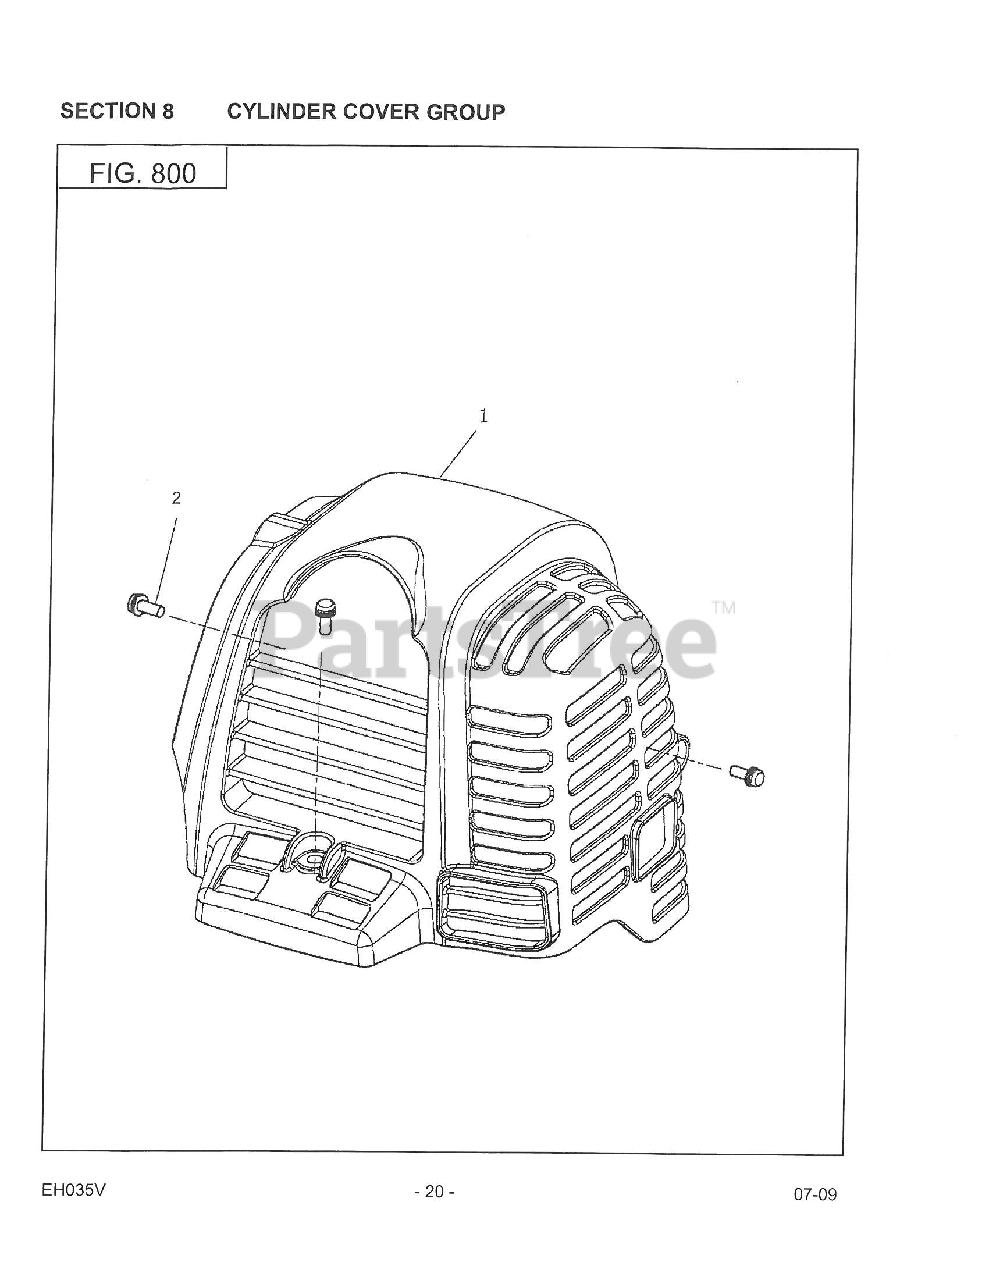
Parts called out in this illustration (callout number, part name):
1	CLEANER PLATE AY
2	AIR CLEANER PLATE
5	PLATE, check valve
6	PLATE, separator
7	GASKET, separator
13	AIR CLEANER ELEMENT
14	AIR CLEANER ELEMENT
17	GASKET, separator
18	AIR CLEANER COVER
